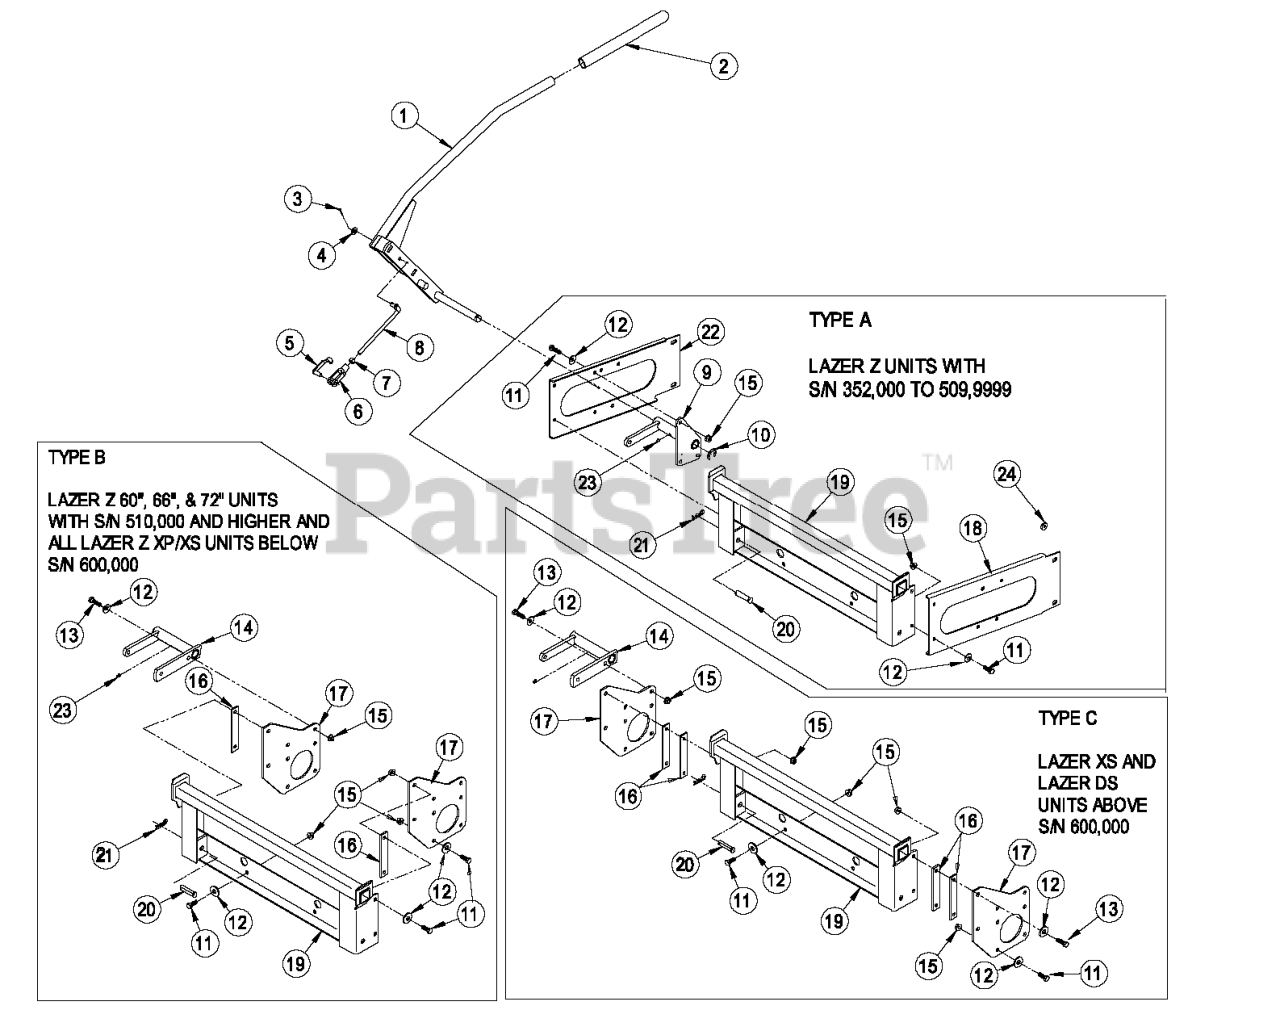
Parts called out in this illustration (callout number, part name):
1	Asm, Handle W/Grip
2	Grip, Handle
3	Pin, Cotter .125 x .75
4	Washer, Flat .406 x .813
5	Pin, Spring Clevis 3/8
6	Yoke, Linkage Brake
7	Nut, HH 3/8-24
8	Link, Handle
9	Wld, Handle Mount (Type A)
11	Screw, HH 3/8-16x1 (Type A)
12	Washer, Spring Disc (Type A)
13	Screw, HH 3/8-16x1.25 (Type B)
14	Wld, Handle Mount (Type B & C)
15	Nut, Whizlock 3/16-16 (Type A)
16	Spacer (Type B)
17	Plate, Bagger Mount (Type B &C)
18	Bracket, Frame RH (Type A)
19	Wld, Bagger Mount
20	Pin, Clevis
21	Pin, Hair
22	Bracket, Frame LH (Type A)
23	Zerk, 1/4-28 Straight
24	Spacer (Type A)
